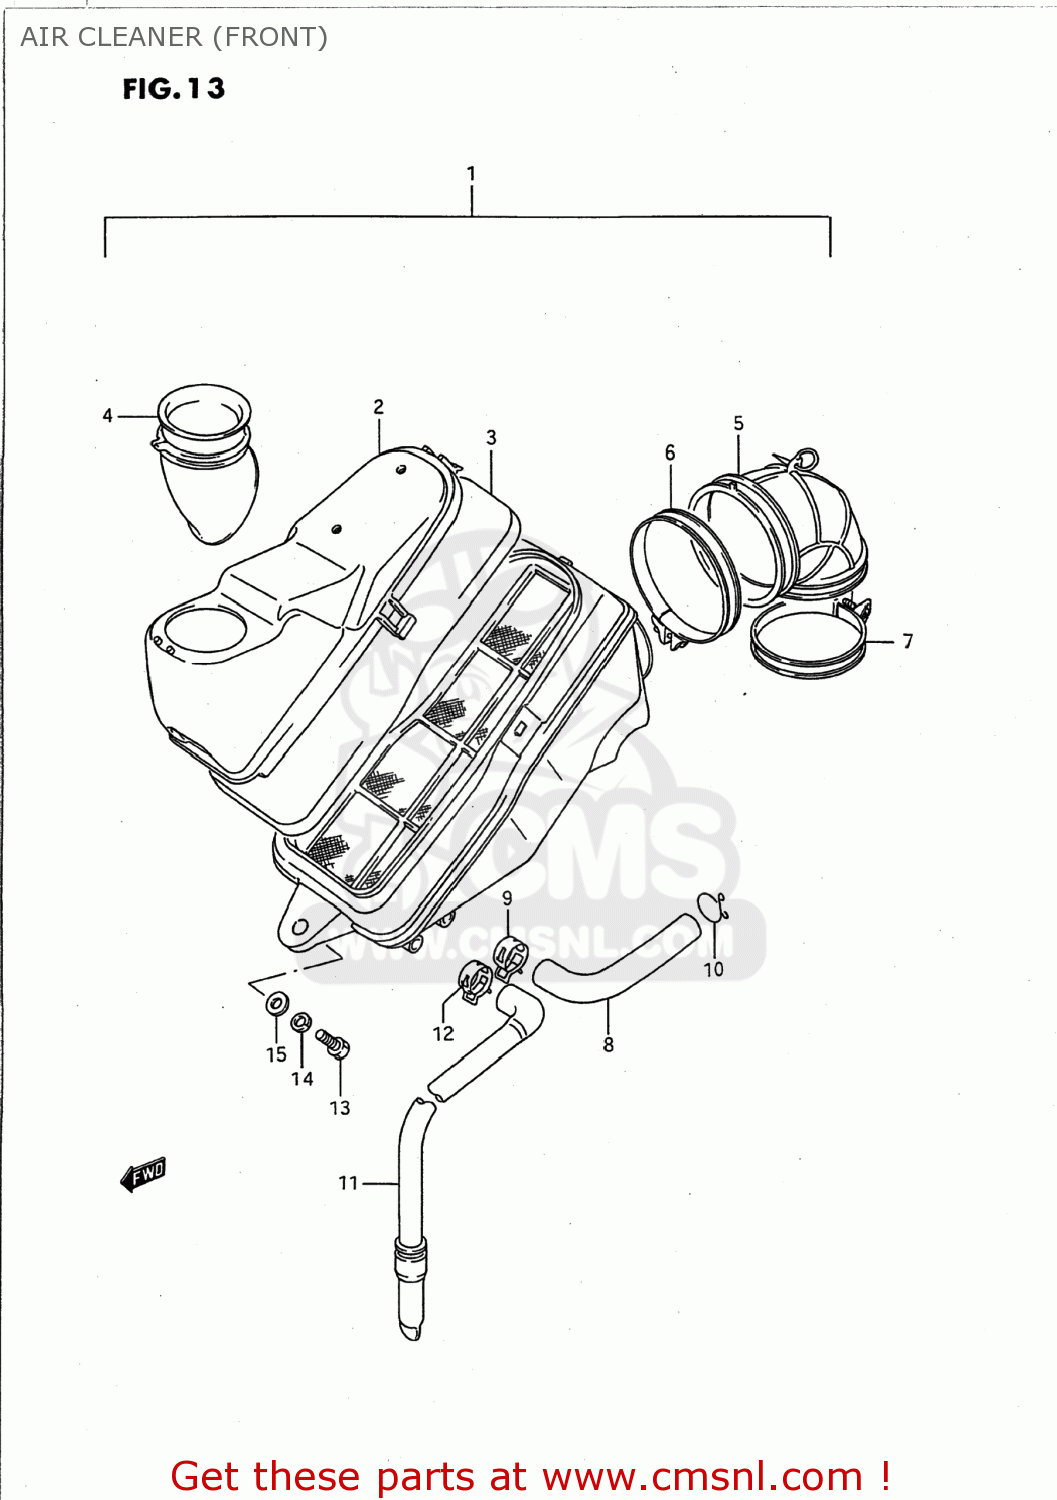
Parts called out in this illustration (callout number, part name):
1	CLEANER ASSEMBLY,AIR
2	CAP,AIR CLEANER
3	FILTER,AIR FR
4	TUBE,INLET
5	TUBE,AIR CLEANER OUTLET
6	CLAMP
7	CLAMP
8	TUBE,BREATHER
9	CLAMP
10	CLIP
11	DRAIN TUBE
12	CLIP
13	BOLT
14	WASHER,LOCK
15	WASHER(6.5X16X1.2)
